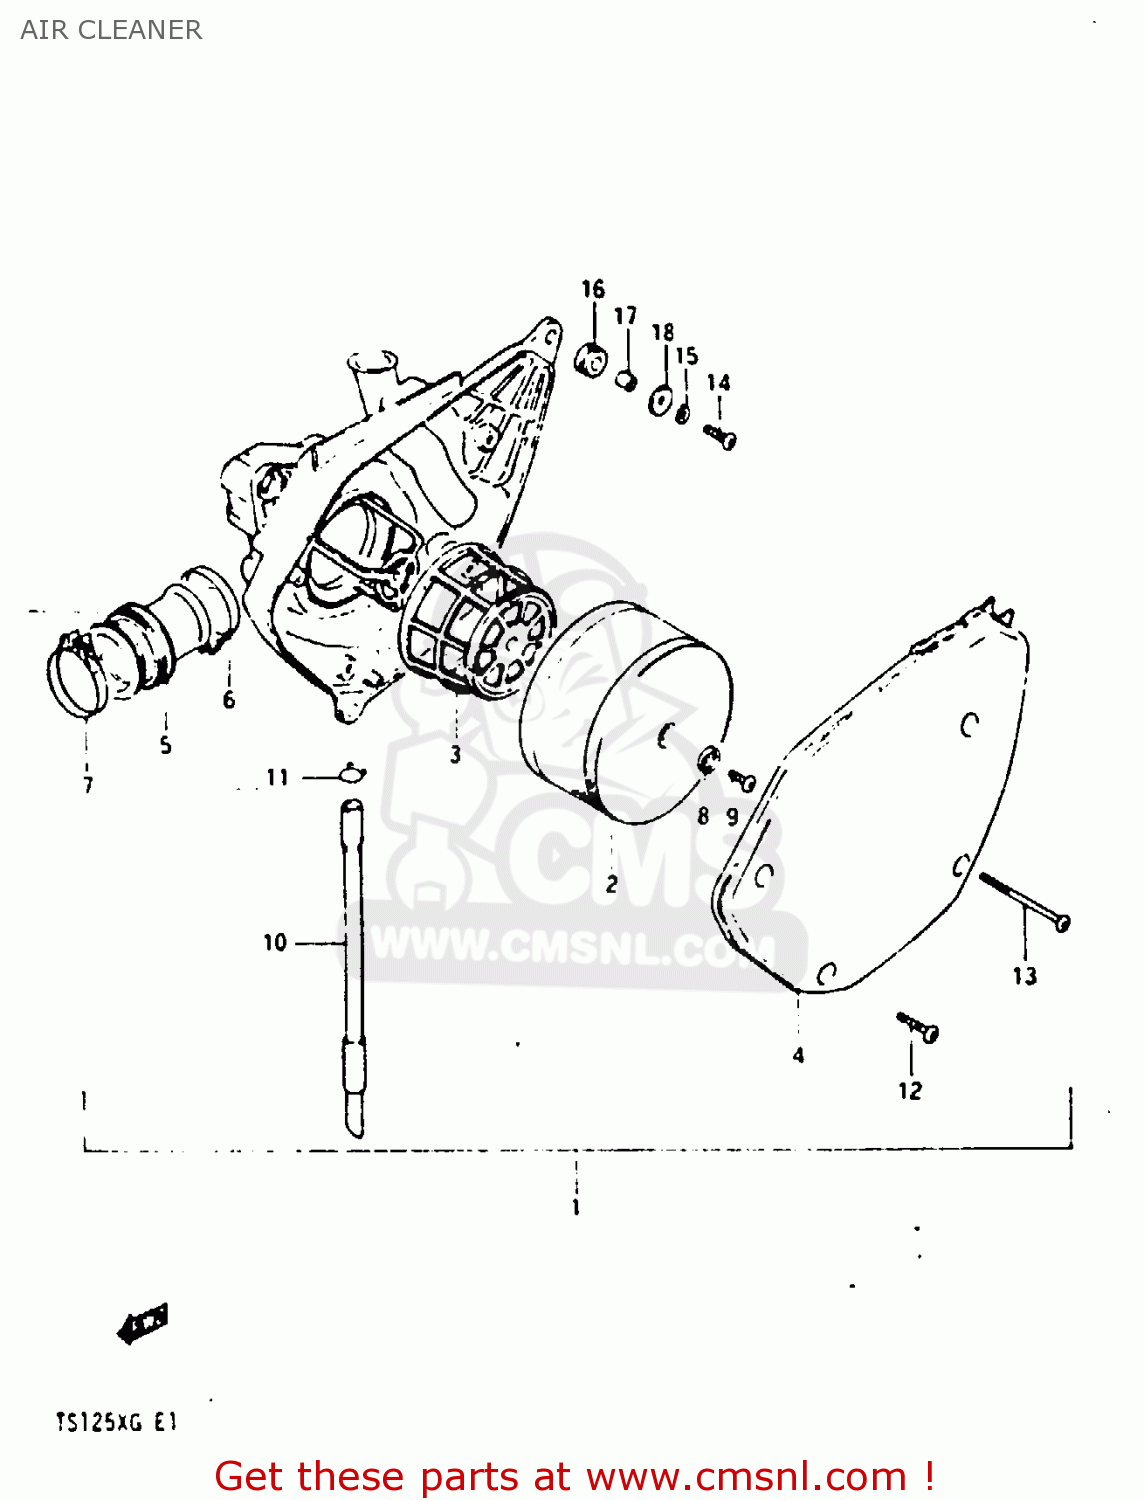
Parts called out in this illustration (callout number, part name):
1	CLEANER ASSY, AIR
2	FILTER
3	HOLDER
4	CAP
5	TUBE, OUTLET
6	CLAMP
7	CLAMP
8	WASHER,FILTER HOLDER
9	SCREW
10	TUBE, DRAIN
11	CLIP
12	SCREW
13	SCREW
14	SCREW
15	WASHER,LOCK
16	CUSHION
17	SPACER (7X9X7)
18	WASHER
